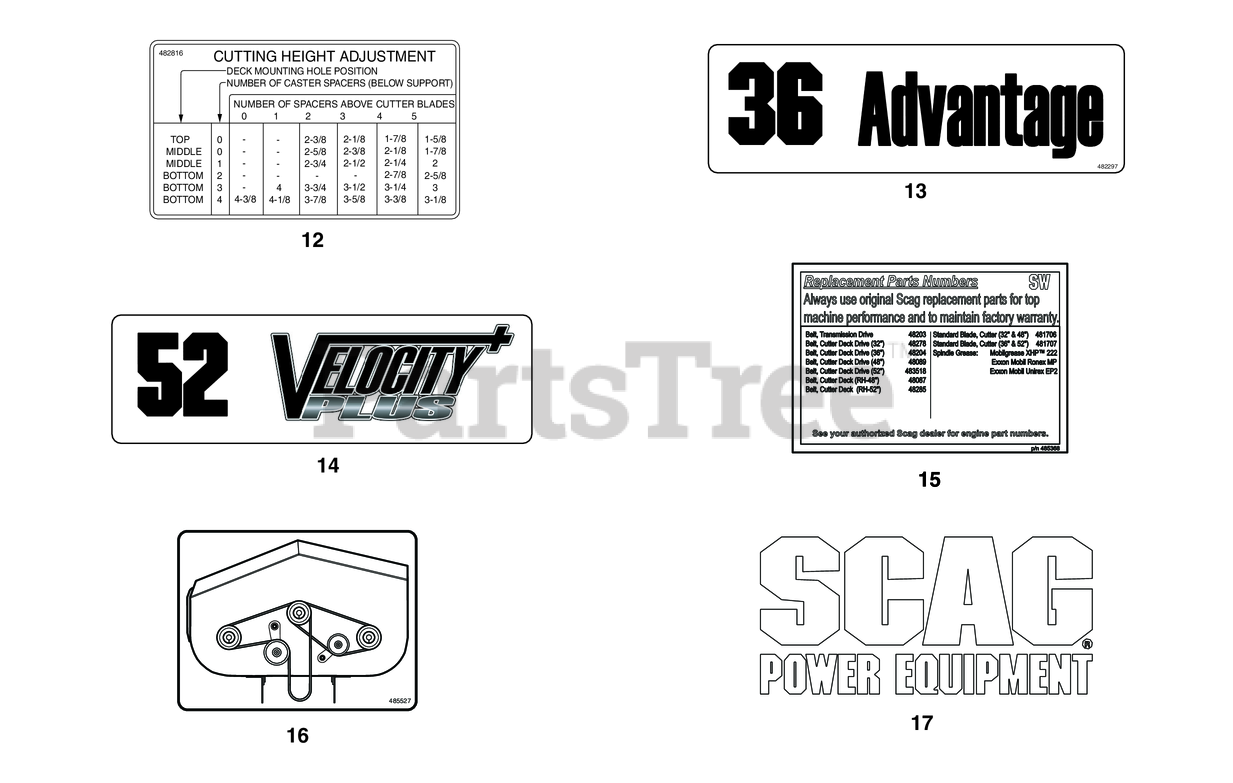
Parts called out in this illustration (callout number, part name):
12	DECAL, HEIGHT OF CUT - SWM
13	Decal, 32
15	Decal, SW Replacement Parts
16	Decal, Belt Routing - 32 & 36A
17	Decal, Scag Power Equipment (Fuel Tank)
